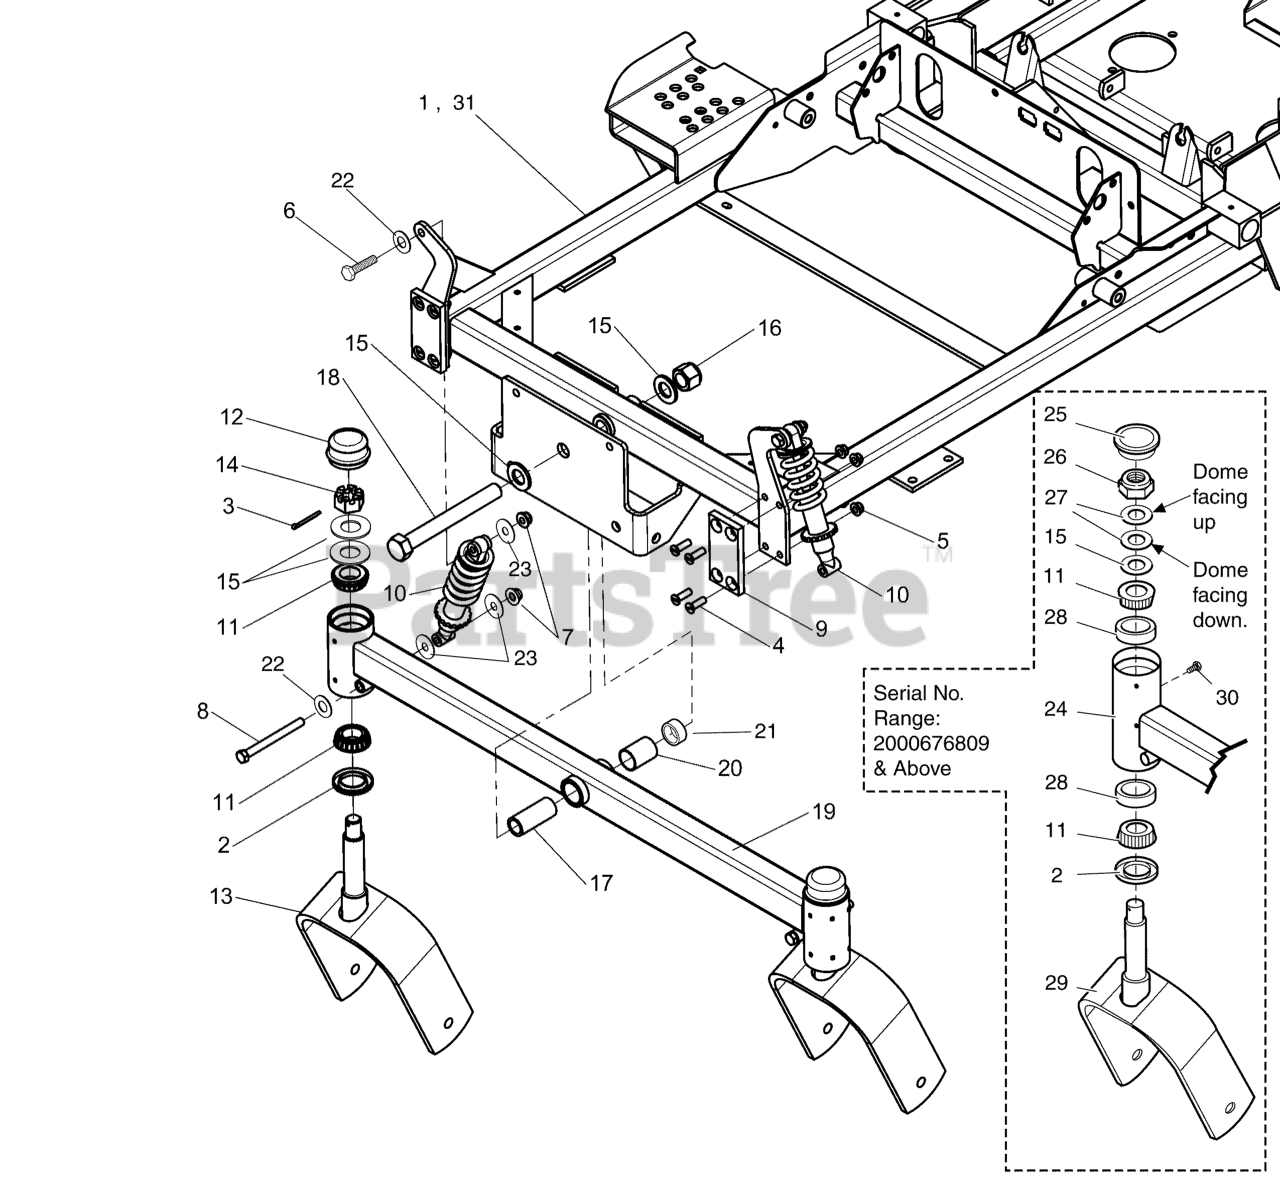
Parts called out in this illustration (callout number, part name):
1	MAIN FRAME ASSEMBLY
2	SEAL, GREASE
3	PIN, COTTER, 1/8 X 1-1/4
4	SCREW, 5/16-18 X 1 PHILLIPS HD, BZ
5	NUT, 5/16-18 Hex Nylon Lock
6	BOLT, 3/8-16 X 1-3/4" GD5 CZ
7	NUT, 3/8-16 Hex Nylock Flange
8	BOLT, 3/8-16 X 4" GD5 CZ
9	FRICTION PLATE
10	SHOCK & SPRING ASSEMBLY
11	BEARING, Tapered Roller
12	CAP
13	CASTER YOKE
14	NUT, 3/4-16 Hex Slotted
15	WASHER, 3/4 SAE
16	NUT, 3/4-16 Hex Nylon Lock
17	SPACER, .75 X 1.00 X 2.38
18	BOLT, 3/4-16 X 6-1/2"
19	KIT, PIVOTING FRONT END
20	PIVOT BEARING
21	PIVOT BEARING
22	WASHER, 3/8 SAE
23	WASHER, 3/8" FENDER
24	WELD, PIVOTING FRONT END - RED
25	CAP, GREASE, LOW PROFILE
26	NUT, 3/4-16 HEX JAM NYLON LOCK
27	BELLEVILLE WASHER, 1.500 X .755
28	CUP, BEARING
29	WELD, CASTER YOKE - RED
30	BOLT, 1/4-28 X 1/2, GD5 YZ
31	WELD, IS1500Z MAIN FRAME
